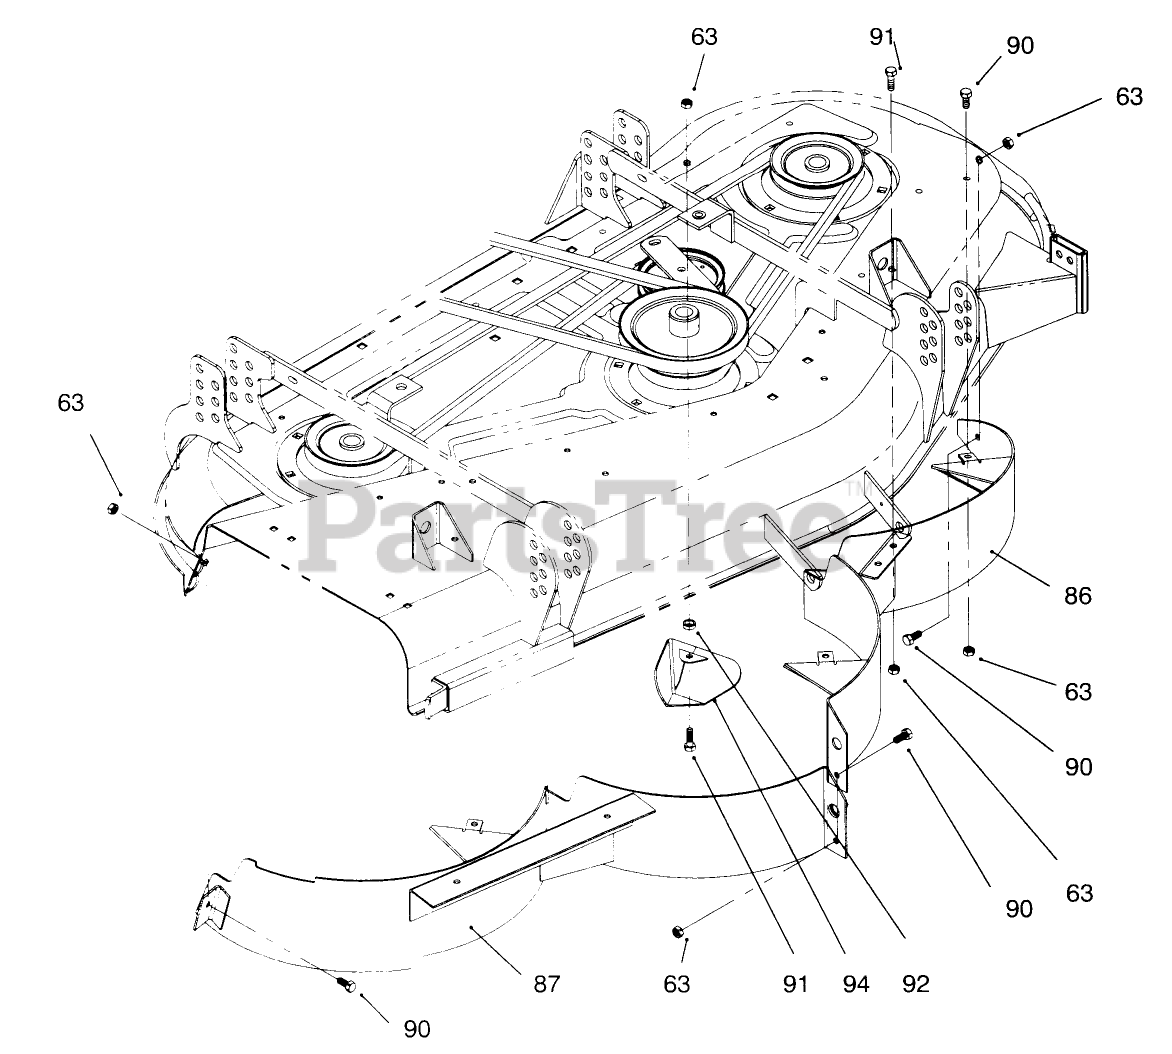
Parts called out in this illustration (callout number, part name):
63	NUT-LOCK, NI
86	LEFT BAFFLE ASM
87	RIGHT BAFFLE ASM
90	SCREW-HH
91	SCREW-HH
92	SPACER
94	PLATE-KICKER
